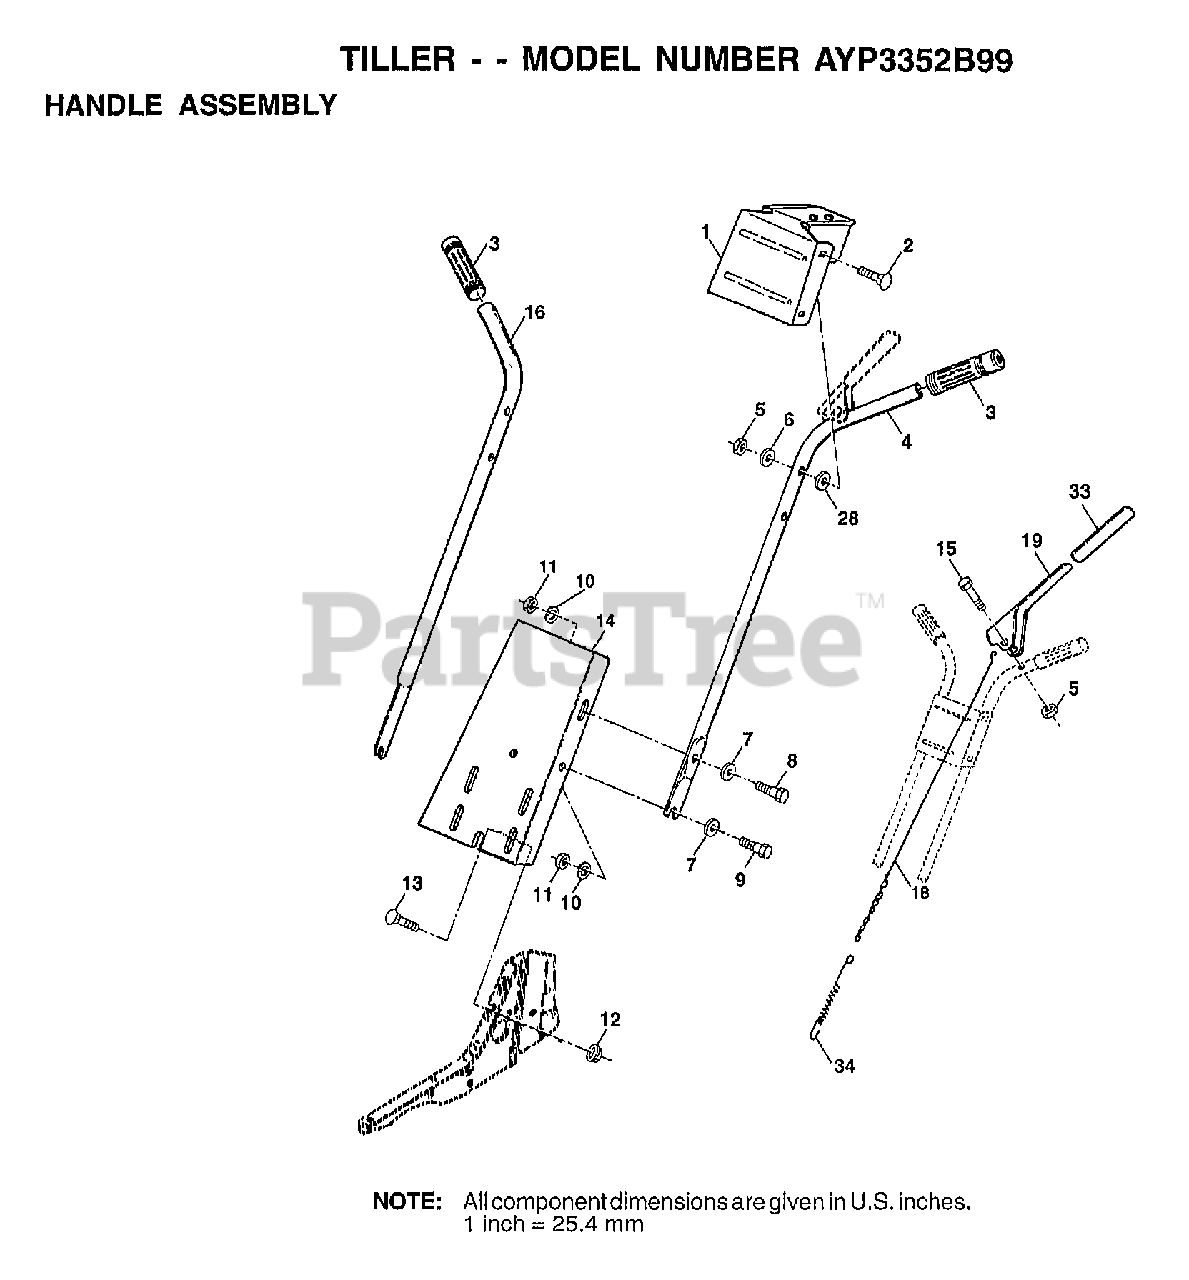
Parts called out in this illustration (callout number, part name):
1	HANDLE BRKT
2	BOLT
4	HANDLE LH
6	WASHER
7	WASHER
9	BOLT
10	LOCKWASHER
11	NUT.HEX.5/16-18
12	NUT
13	BOLT
14	PANEL. HANDLE
15	BOLT.HEX.5/16-1.5
16	HANDLE RH
19	LEVER.CONTROL.TINE
28	WASHER
33	GRIP T
34	SPRING EXT TI
